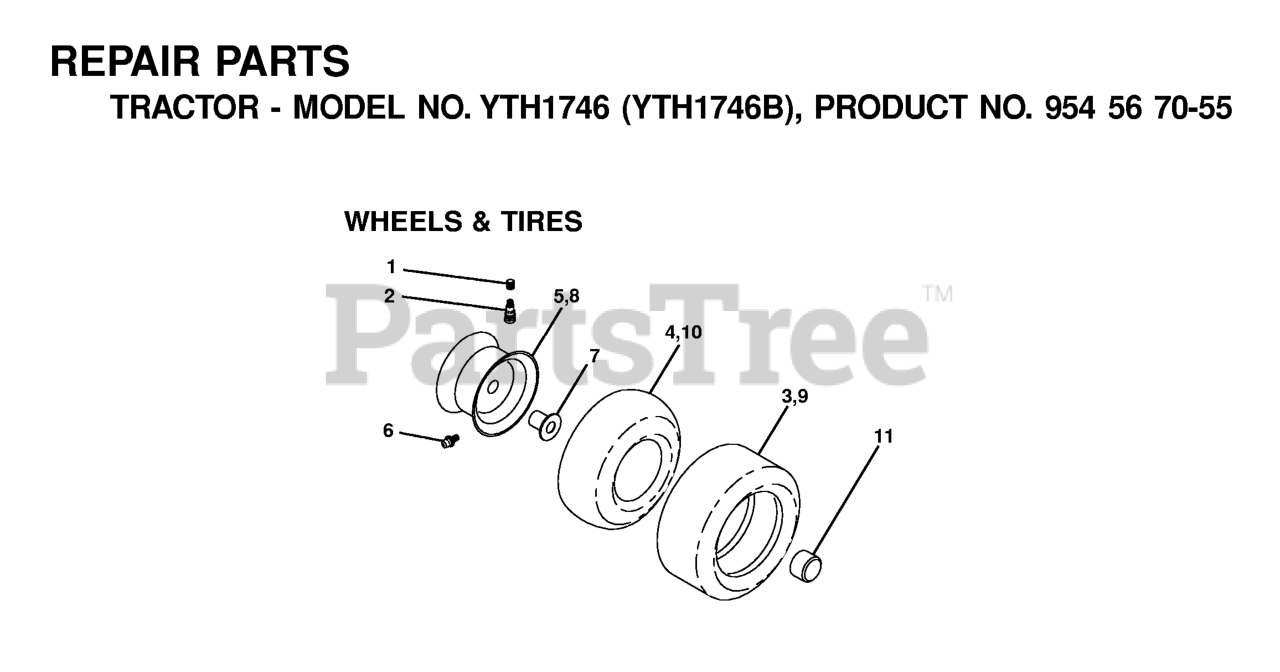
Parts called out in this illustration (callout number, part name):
2	VALVE STEM LT
3	TIRE HEAVY DUTY
4	TUBE.5.3/4.5/6
5	RIM ASM 6" FRONT SILVER
6	FITTING LT
7	BEARING T
8	RIM ASM 8" REAR SILVER
9	TIRE.TS.20X10-8
10	TUBE
11	CAP, AXLE BLK
